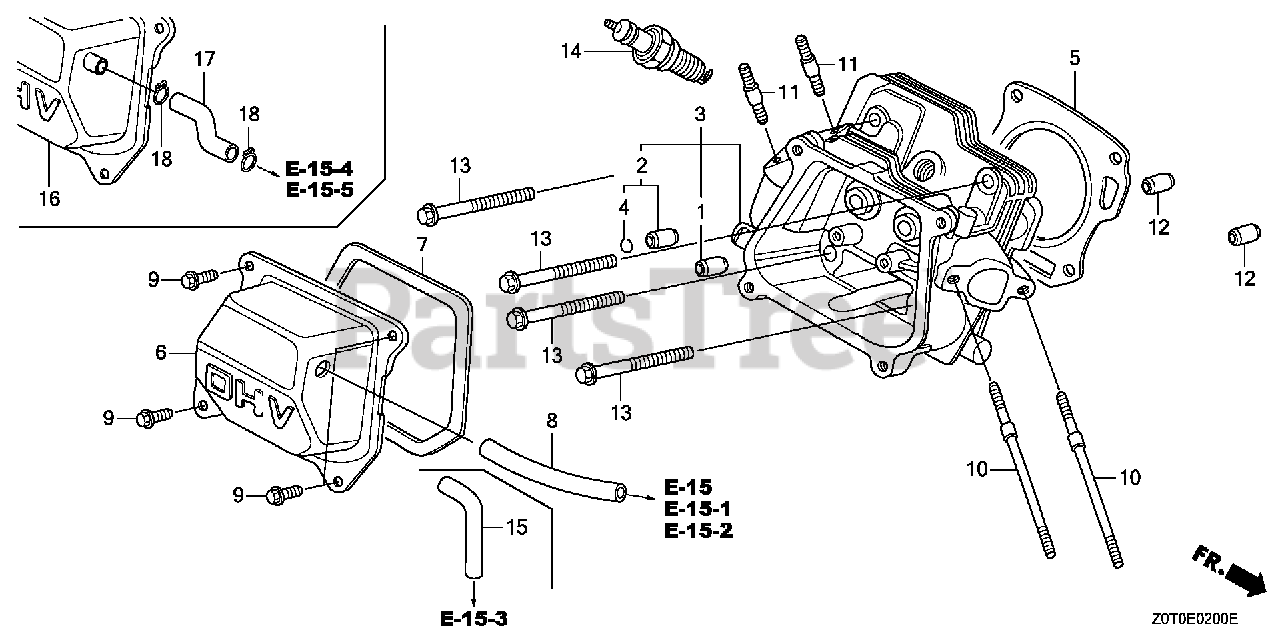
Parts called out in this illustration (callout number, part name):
1	GUIDE, VALVE (OVER SIZE)
2	GUIDE, EX. VALVE (OVER SIZE)
3	CYLINDER HEAD
4	CLIP, VALVE GUIDE
5	GASKET, CYLINDER HEAD
6	COVER, HEAD
7	GASKET, HEAD COVER
8	TUBE, BREATHER
9	BOLT, FLANGE (6X12) (CT200)
10	BOLT, STUD (6X112)
11	BOLT, STUD (8X32)
12	PIN, DOWEL (10X16)
13	BOLT, FLANGE (8X60)
14	SPARK PLUG (BPR6ES) (NGK)
